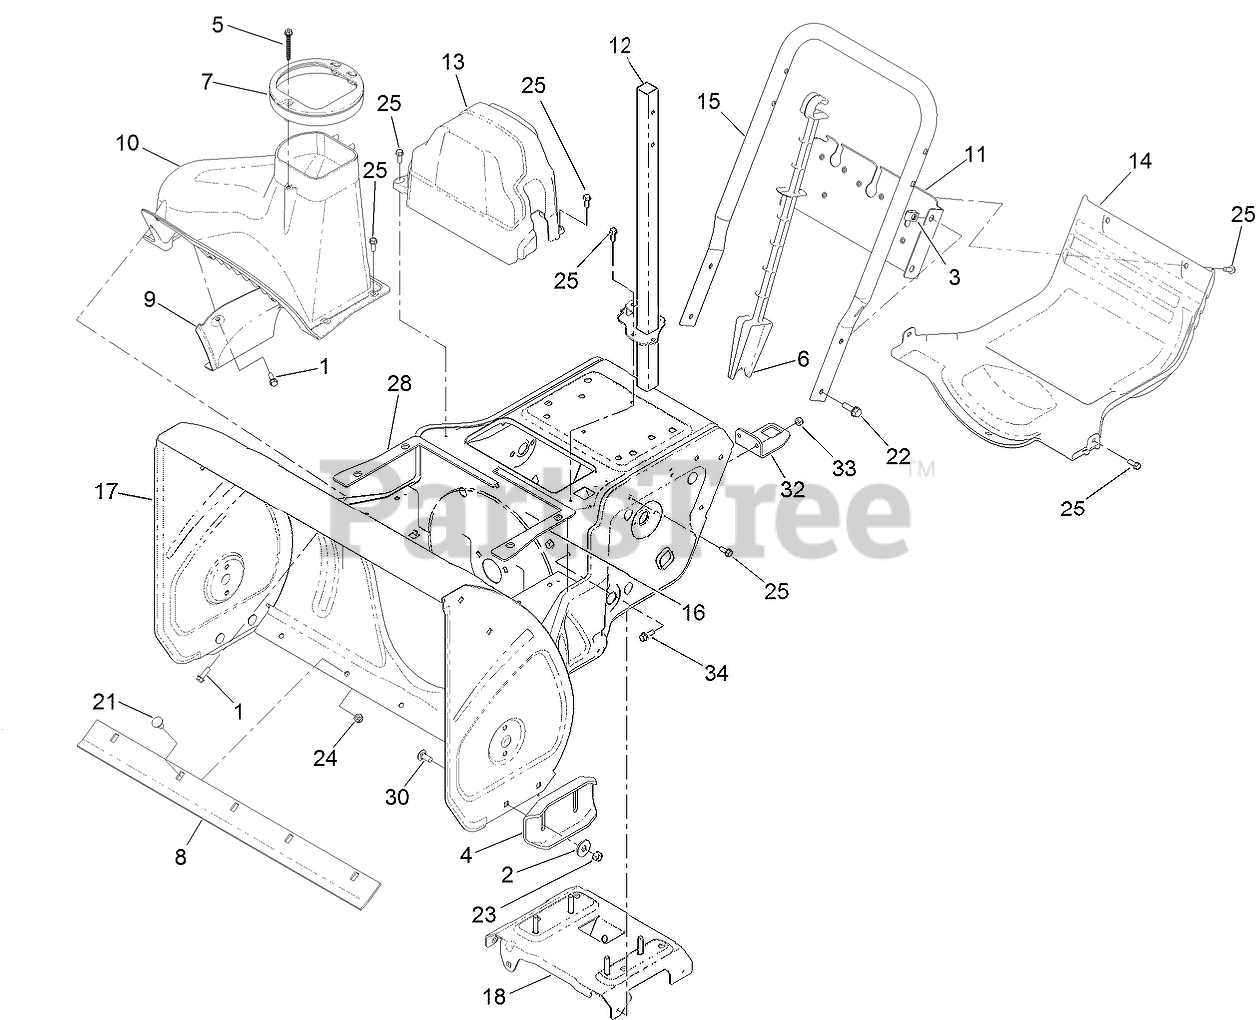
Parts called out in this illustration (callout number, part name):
1	SCREW-PLASTITE, HWH
2	WASHER-FLAT
3	NUT-U
5	SCREW-HWH, PLASTITE
6	STICK-CLEANOUT
7	GUIDE-CHUTE
8	SCRAPER-26 INCH
9	COVER-LINER
11	BRACE-FRAME
12	SUPPORT-CHUTE
13	COVER-BELT
14	COVER-LOWER
15	HANDLE-LOWER, CTS
16	SEAL-HOUSING, LH
17	FRAME ASM
18	BRACE-FRAME
21	BOLT-CARR
22	SCREW-HHF
23	NUT-HEX
24	NUT-HEX
25	SCREW-HWH
28	SEAL-HOUSING, RH
30	BOLT-CARR
32	BRACKET-POST, CHUTE
33	SCREW-HHF
34	NUT-HEX
